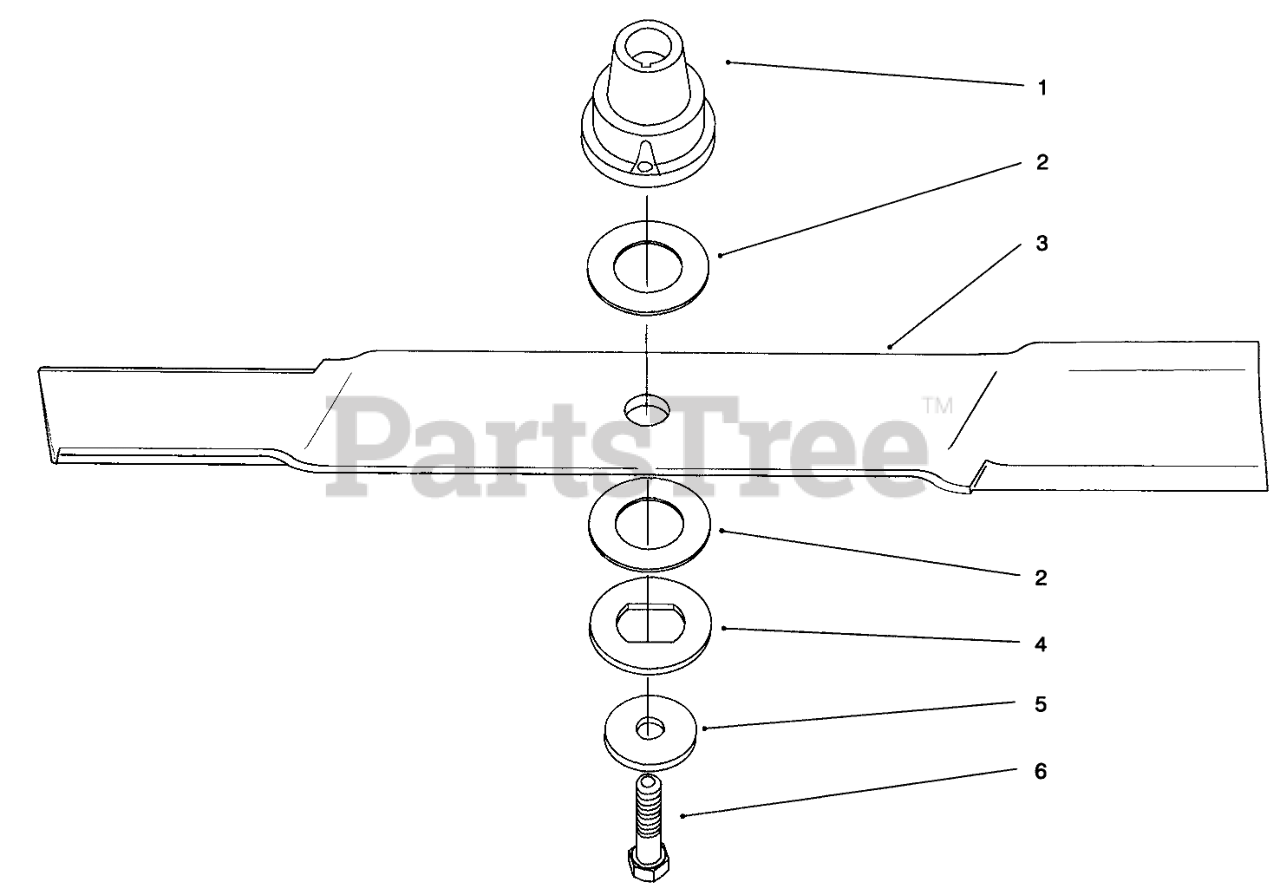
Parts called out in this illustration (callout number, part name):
1	RETAINER - BLADE
2	WASHER - FRICTION
3	BLADE - 43 CM
4	WASHER - PRESSURE
5	WASHER - SPRING
6	SCREW-BLADE
